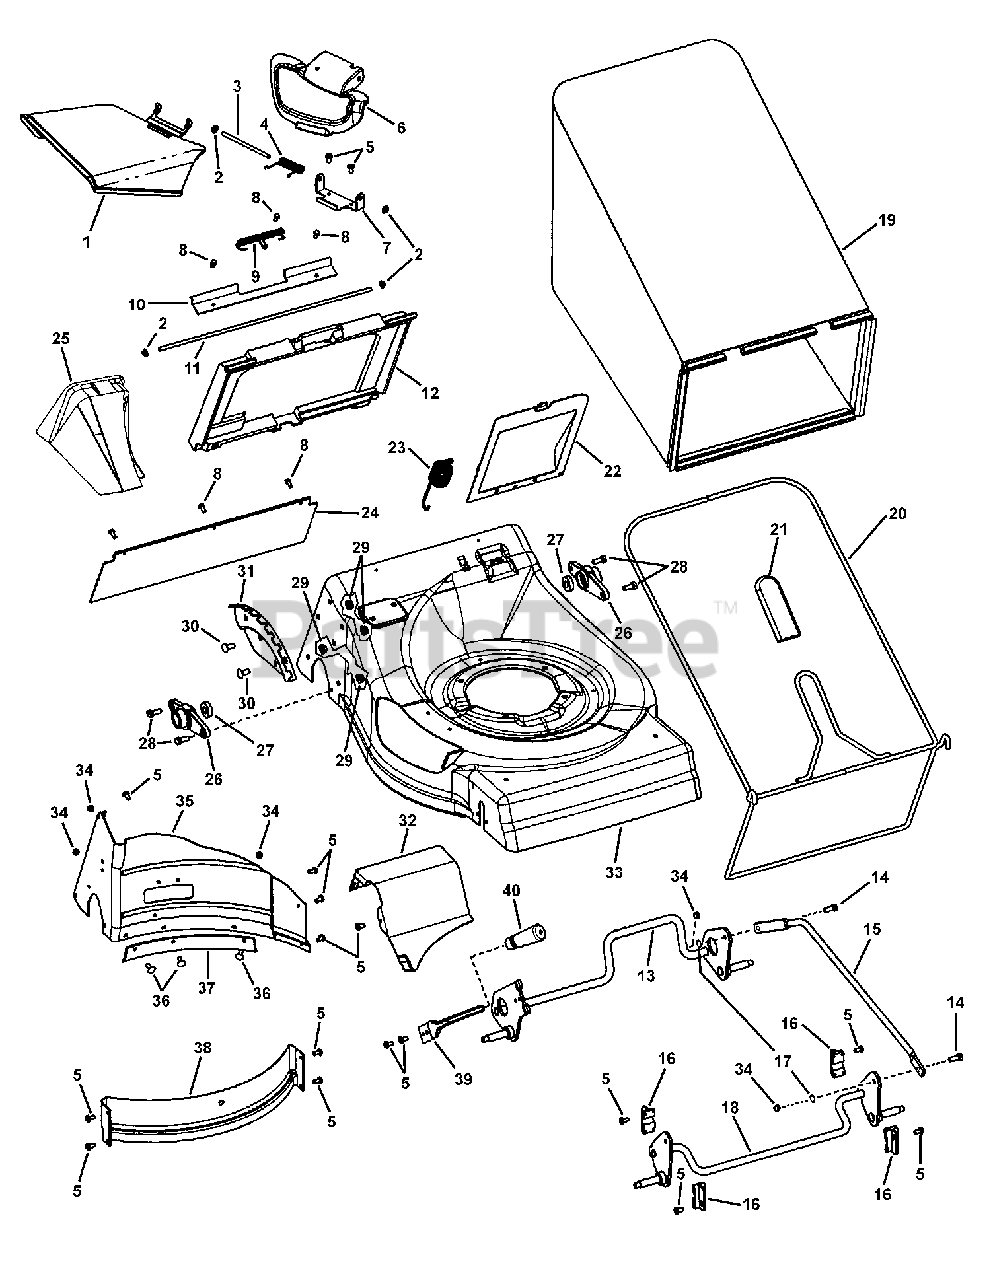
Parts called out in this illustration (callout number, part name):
1	CHUTE, 21" Side Discharge
2	PUSHNUT, 1/4"
3	ROD, Pivot, Mulch Cover
4	SPRING, Torsion, Chute
5	SCREW, 1/4-20 x .550 Pan Head Torx, Self-Tap
6	COVER, 21" Mulching
7	BRACKET, Chute Deflector
8	SCREW, #10-24 x 1/2" Hex Washer Self-Tap, SEMS
9	SPRING, Torsion
10	SPACER, Rear Door, 21"
11	ROD, Pivot, Rear Door, 21" RD
12	DOOR, 21" Black
13	WELDMENT, Rear Crossbar 21" WBM, RD, YZ
14	BOLT, Shoulder, #10-24 Thread
15	ROD, Lifter Link
16	BUSHING, Front, 21"
17	PUSHNUT, 1/4 Black
18	WELDMENT, Front Crossbar 21" WBM, RD, YZ
19	GRASSBAG, 21" Rear Discharge
20	BAG FRAME, 21" RD WBM
21	GRIP, Rectangular (Black)
22	TRANSMISSION COVER, Rear 21"
23	SPRING, Extension, Height-of-Cut Assist
24	DEFLECTOR, Rear, 21" WBM, RD
25	PLUG, Mulching
26	BEARING HOLDER, 21" WBM,RD
27	BALL BEARING, Axle
28	SCREW, 5/16-18 x 3/4" Hex Head Cap, GR 5 YZ
29	NUT, 5/16-18 Hex Flange Lock, GR 5, YZ
30	BOLT, 5/16-18 x 3/4" Round Head Short Square Neck, GR 5, YZ
31	INDEX PLATE, Height-of-Cut, 21" WBM, RD
32	BAFFLE, Right Rear, 21" WBM, RD
33	DECK, 21" Rear Discharge, Non-Electric Start
34	NUT, #10-24 Hex Nyloc
35	BAFFLE, Left Rear, 21" RD, WBM
36	BOLT, #10-24 x 5/8" Flat Head Square Neck, YZ
37	BAFFLE, Extension, 21" RD WBM
38	BAFFLE, Front 21" WBM, RD
39	LEVER, Spring Height-of-Cut
40	GRIP, Height-of-Cut
